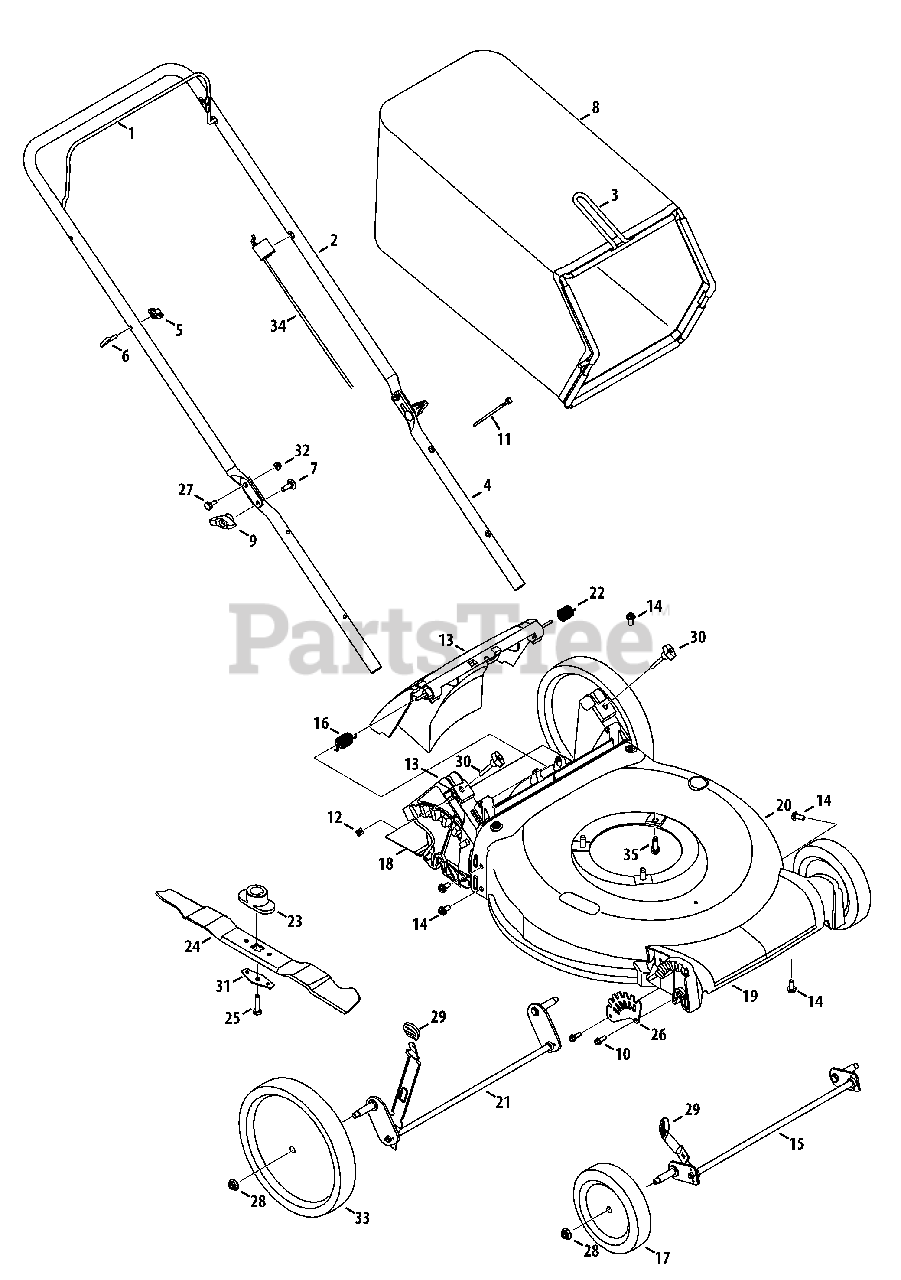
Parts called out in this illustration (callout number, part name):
1	Blade Control
2	Upper Handle
3	Grass Catcher Frame
4	Lower Handle
5	Wing Nut
6	Rope Guide
7	Carriage Screw, 5/16-18
8	Grass Bag
9	Wing Knob
10	Screw, 1/4-15 x .750
11	Cable Tie
12	Nut, Sq., 1/4-20
13	Rear Discharge Door Assembly
14	Screw, 5/16-14 x .750
15	Front Axle Assembly
16	Torsion Spring - RH
17	Front Wheel Gray
18	Trail Shield
19	Front Cover
20	Deck - 21"
21	Rear Axle Assembly
22	Torsion Spring - LH
23	Blade Adapter
24	Mulching Blade
25	Screw , 3/8-24 x 1.50
26	Front Height Adjuster Plate
27	Sldr. Screw, .375 x .126 x 1/4-20
28	Flange Lock Nut, 3/8-16
29	Adjustment Lever Knob
30	Wing Nut
31	Blade Bell Support
32	Nut, Flange Lock, 1/4-20
33	Rear Wheel
34	Control Cable
35	TT Sems Screw, 3/8-16 x 1.0
